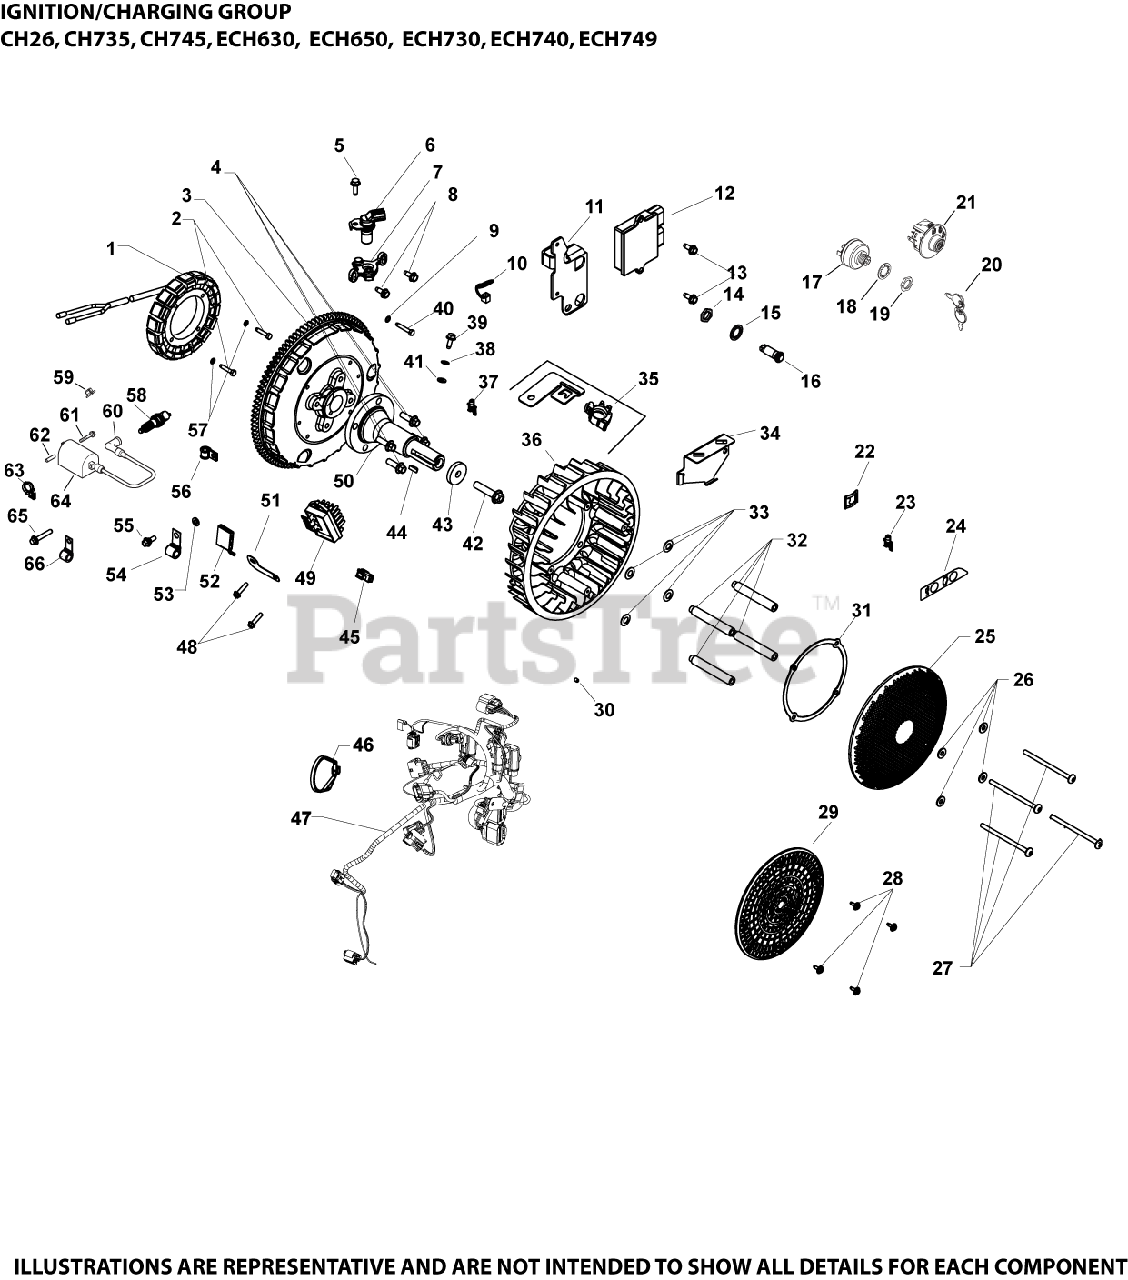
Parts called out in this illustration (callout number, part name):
1	KIT, 25 AMP STATOR ASSY.
3	FLYWHEEL ASSEMBLY
5	SCREW, THREAD FORMING
6	SENSOR, SPEED
7	BRACKET, SENSOR MOUNT-(#2512616S)
8	SCREW, THREAD FORMING
9	WASHER, INT TOOTH LOCK #10
10	CAP, CONNECTOR
11	BRACKET, ECU
12	MODULE, ECU
13	SCREW, THREAD FORMING
25	KIT, GRASS SCREEN
30	SCREW, FLG M10X1.5X45 - (#25086361S)
35	KIT, MOUNTING CLIP
36	FAN USE 24 755 253-S
37	TIE, WIRE
38	WASHER, INT TOOTH LOCK 1/4"
40	SCREW, THREAD FORMING
41	WASHER, FLAT 1/4" (O.D. 1/2")
43	WASHER, FLAT 13/32"
44	KEY, 3/16" X 5/8"
47	HARNESS, WIRING ASSEMBLY
48	SCREW, HEX FLANGE HI-LO
49	REGULATOR, RECTIFIER USE 25 403 32-S
51	BRACKET, GROUND STRAP USE 24 518 12-S
52	CONNECTOR
54	CLIP, CABLE
55	BOLT, SHOULDER
57	WASHER, FLAT 3/16"
58	PLUG, SPARK (STD)
64	COIL, IGNITION - EFI
65	SCREW, FLG M6X1.0X34
66	CLIP, CABLE
